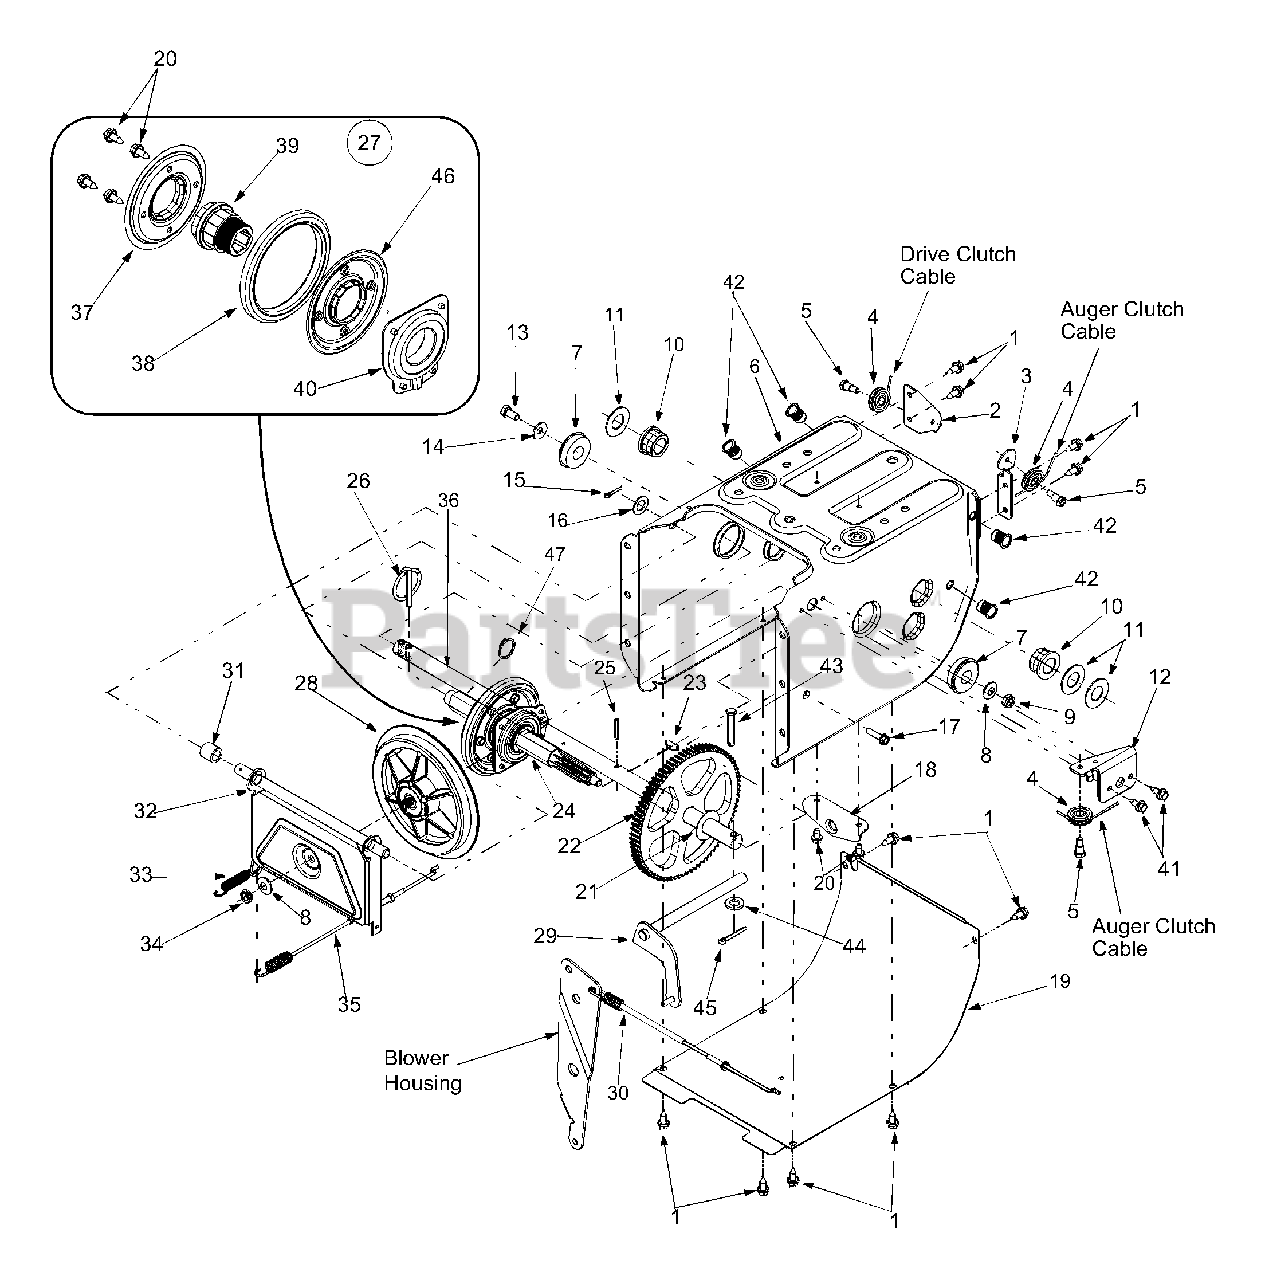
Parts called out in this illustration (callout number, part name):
1	Hex Screw
5	Hex Screw 1/4-28
6	Frame Assembly
7	Ball Bearing
8	Bell Washer
9	Lock Jam Nut
10	Hex Flange Bearing
11	Flat Washer
14	Bell Washer .340 ID x .872 OD
15	Cotter Pin
16	Flat Washer .536 ID x .930 OD
17	Hex Washer Screw 1/4-20
21	Flat Washer .760 ID x .50 OD
24	7-Tooth Shaft
25	Rolled Pin
26	Klik Pin
27	Friction Wheel Assembly
28	Friction Disc Wheel
29	Wheel Shift Rod Assembly
30	Drive Cable
31	Spacer
34	Jam Nut 3/8-24
35	Drive Cable
36	Axle 13" Wheels
37	Friction Plate
38	Friction Wheel Rubber
39	Friction Wheel Hub
40	Friction Wheel Bearing
41	Tap Screw 1/4-20
42	Insert Nut 5/16-18
43	Clevis Pin
44	Flat Washer .281 ID x .50 OD
45	Cotter Pin
46	Friction Plate
47	Snap Ring
